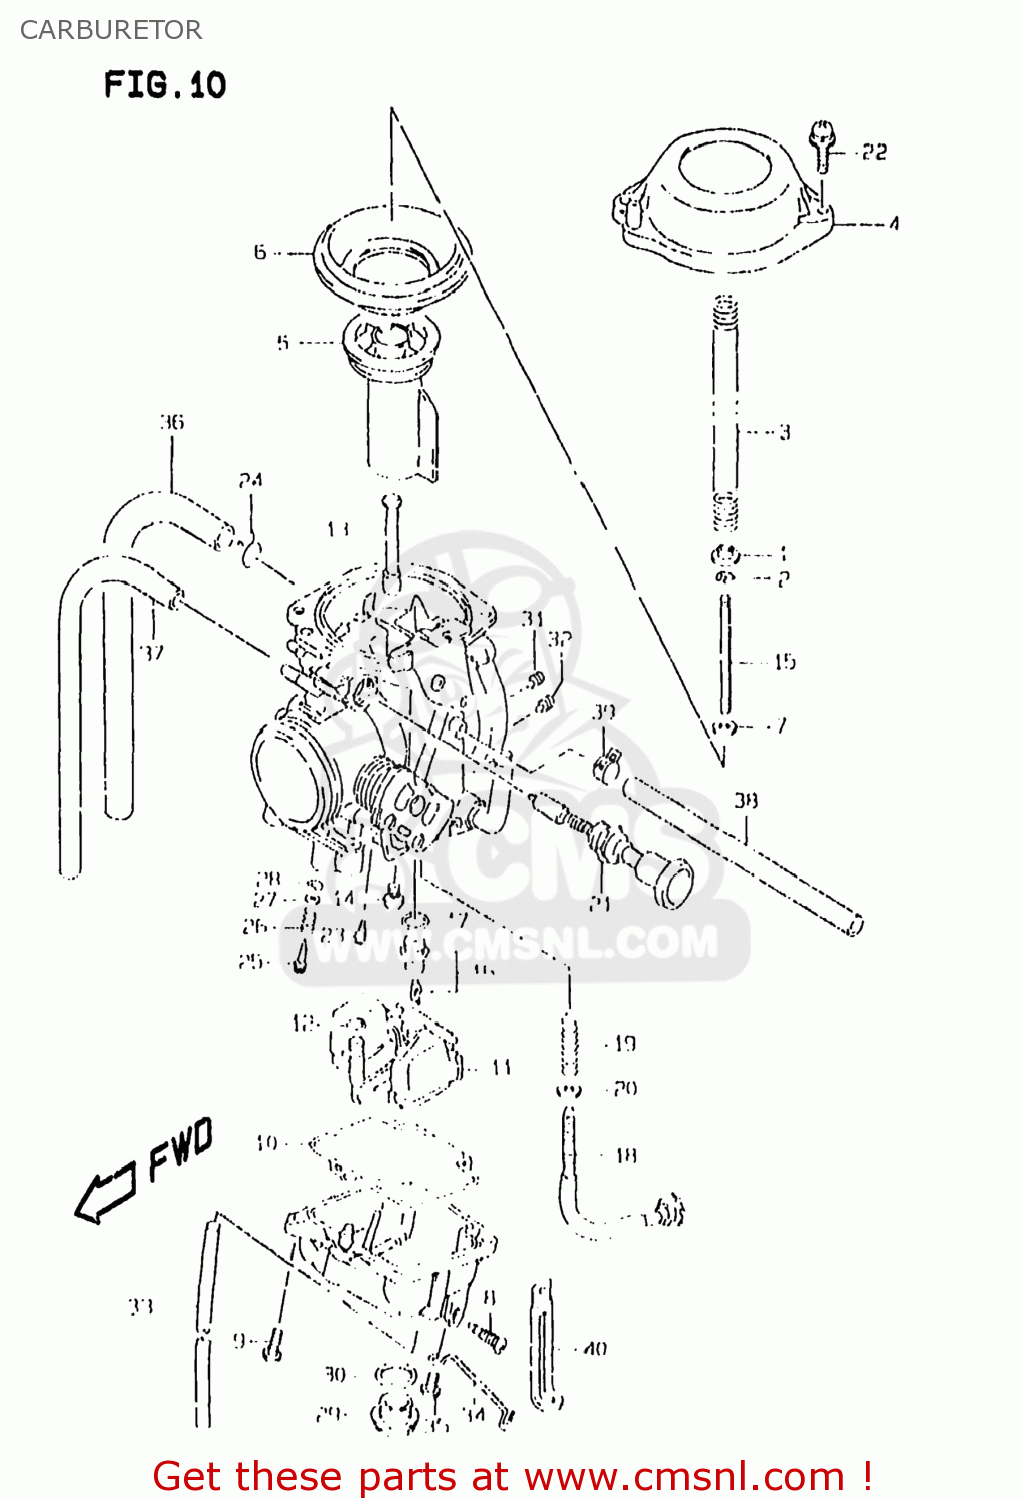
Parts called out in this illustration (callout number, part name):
0	CARBURETOR ASSEMBLY
1	RING
2	E RING
3	SPRING
4	COVER,DIAPHRAGM
5	VALVE PISTON
6	DIAPHRAGM
7	RING
8	SCREW,DRAIN
9	SCREW
10	GASKET,FLOAT CHAMBER (NAS)
11	FLOAT ASSY
12	O RING
13	JET,NEEDLE(O-6M)
14	JET,MAIN(127.5)
15	NEEDLE,JET
16	VALVE ASSY,NEEDLE
17	O-RING,NEEDLE VALVE
18	ADJUSTER
19	SPRING,THROTTLE SCREW
20	WASHER,STARTER SHAFT
21	PLUNGER ASSEMBLY
22	SCREW
23	JET,PILOT(37.5)
24	CLIP
25	SCREW,PILOT
26	SPRING
27	WASHER
28	O RING,PILOT AIR SCREW
29	SCREW,GUIDE
30	O RING,DRAIN PLUG
31	JET,AIR(1.3)
32	JET,AIR(0.6)
33	HOSE(3X5X600)
34	CLIP
35	SCREW
36	HOSE(7X11X600)
37	HOSE(4.5X8.5X600)
38	HOSE(5X8.2X600)
39	CLIP
40	CLAMP(L:45)
